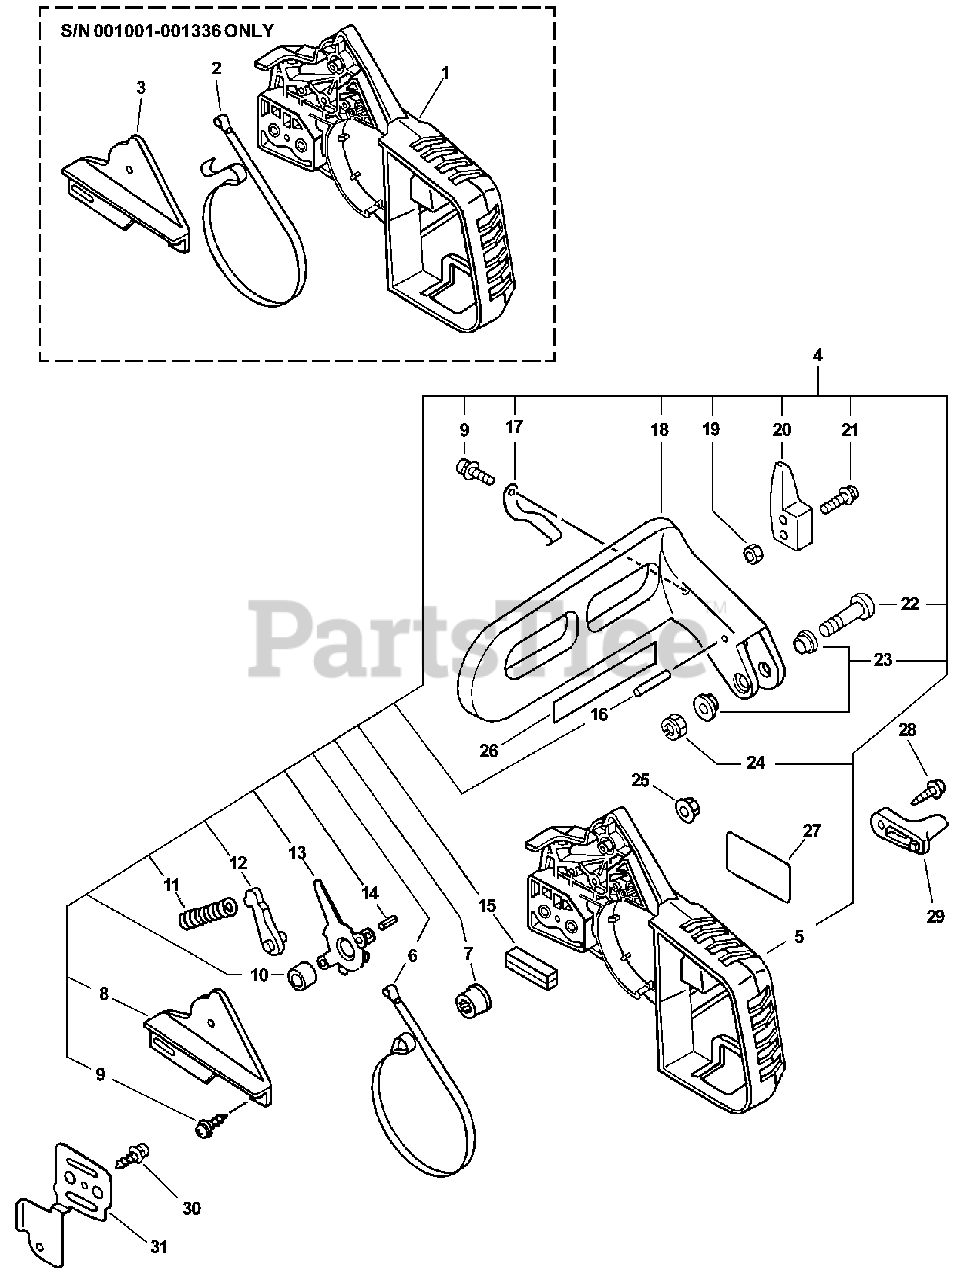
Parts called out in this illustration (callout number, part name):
1	GUARD, SPROCKET
2	BAND, BRAKE
3	COVER, BRAKE
4	CHAIN BRAKE ASSY
5	GUARD, SPROCKET
6	BAND, BRAKE
7	ADJUSTER, BRAKE
8	COVER, BRAKE
9	SCREW 4×10
10	SPACER 8×12×9
11	SPRING, COMPRESSION
12	STOPPER, BRAKE
13	LEVER, BRAKE
14	PIN, SPRING 4×8.8
15	SEAL, BRAKE
16	ROLLER 4×23.8
17	SPRING, FLAT
18	LEVER, BRAKE
20	WEIGHT, BRAKE
21	SCREW 4×20
22	SCREW 5×30
23	COLLAR 5.3×10×13×L5
24	NUT, LOCK M5
25	NUT, FLANGE M6
26	LABEL, BAR & CHAIN
27	LABEL - MODEL
28	SCREW, TAPPING 5×20
29	CHAIN CATCHER
30	SCREW 4×10
31	PLATE, GUIDE
